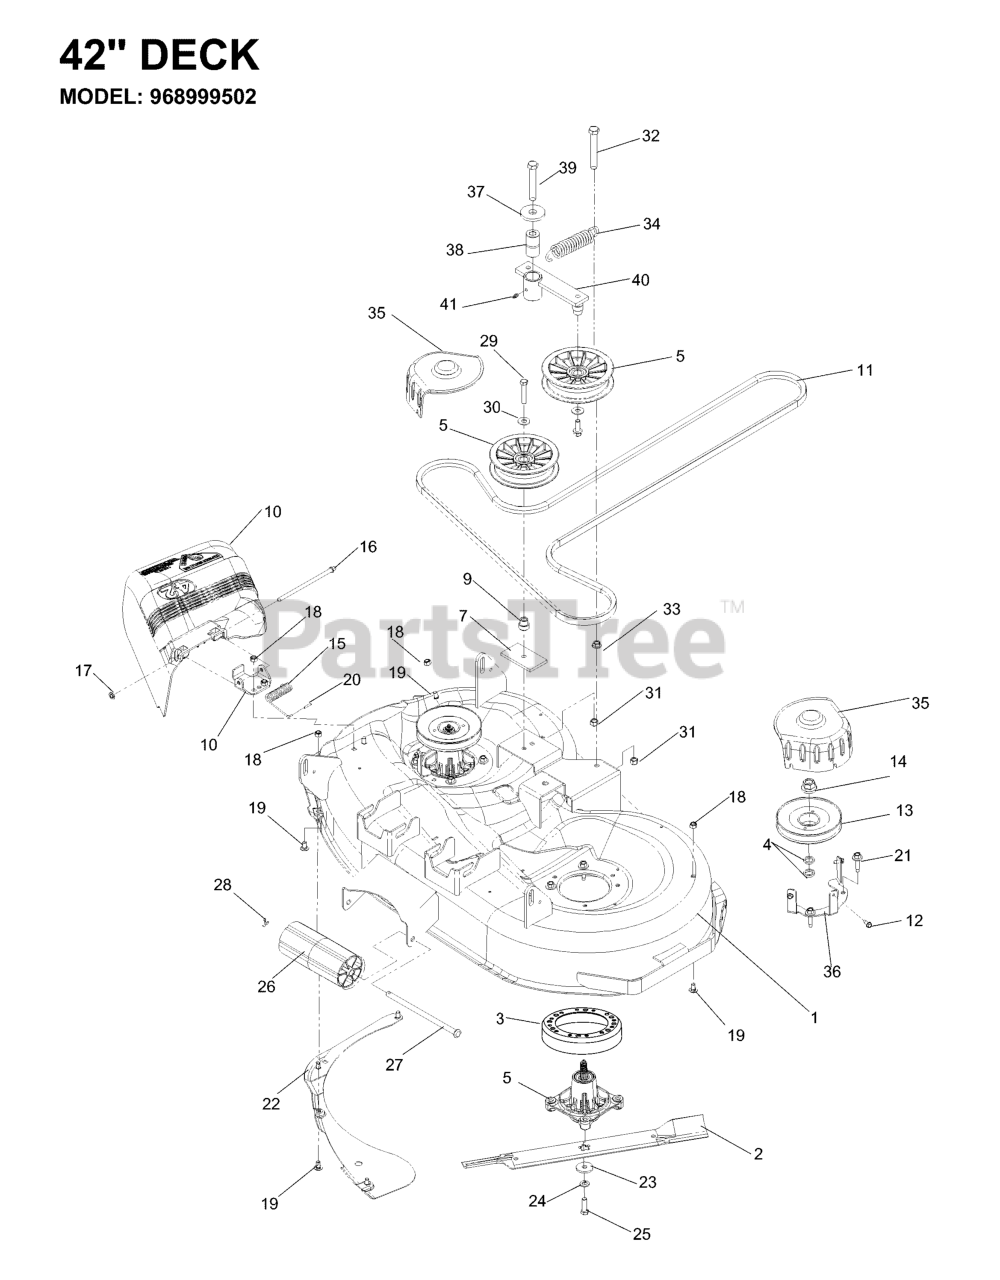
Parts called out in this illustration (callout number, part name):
1	DECK W/DECAL 42" ORANGE
2	BLADE 42" MULCHING STD
3	STRIPPER-ROUND-UNIVERSAL
4	WASHER-SPACER
5	CUTTER HOUSING
6	IDLER
7	SUPPORT PLATE
8	IDLER BUSHING
9	BRKT.DEFLECTOR.38"2005+
10	DEFLECTOR 42
11	BELT, DECK
12	SCREW 1/4 X 5/8
13	RP.PULLEY, DECK
14	LOCKNUT - 9/16
15	SPRING, TORSION DEFLECTOR
16	ROD, HINGE
17	PUSH NUT
18	NUT 5/16 NYLOC
19	CARRIAGE BOLT 5/16C X 5/8"
20	CAP-SLEEVE
21	WASHER HEAD SCREW
22	BAFFLE VORTEX 42
23	WASHER, HARDENED
24	WASHER, LOCK HVY HLCL 3/8
25	BOLT, HEX 3/8-24 X 1.25 GR 8
26	NOSE ROLLER-48"
27	NOSE ROLLER ROD
28	RP_COTTER PIN 1/8 X 3/4
29	HCS 3/8C X 2
30	WASHER 3/8 FLAT
31	NUT 3/8-16 NYLOC
32	HCS 3/8C X 2 1/2
33	NUT 3/8C WHIZ
35	SPINDLE COVER
36	MOUNT, BELTSHIELD
37	WASHER, SUPPORT
38	PIVOT BUSHING
39	HCS 1/2C X 3 1/4
41	ZERK
